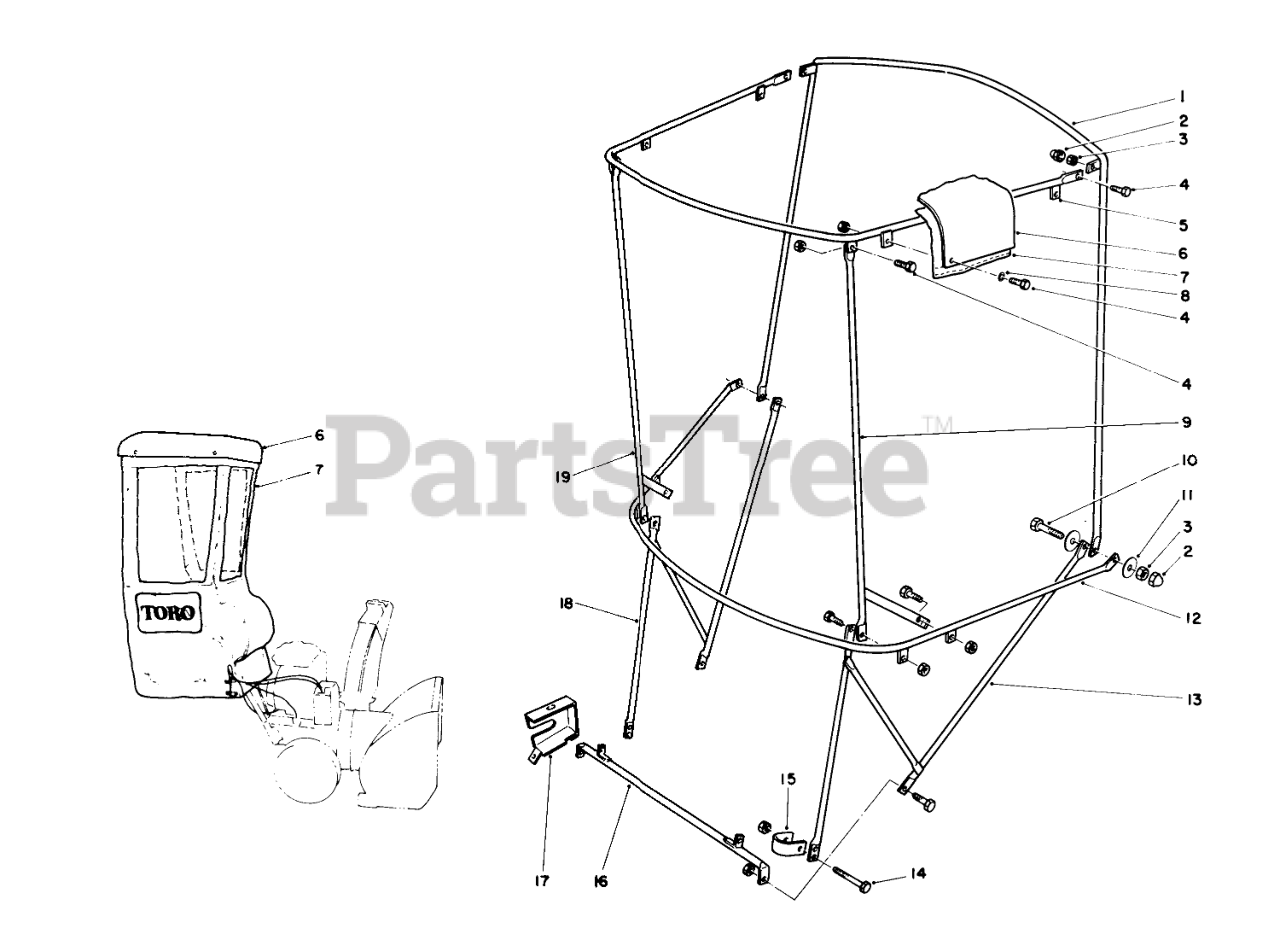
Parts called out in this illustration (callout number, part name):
1	VERTICAL BOW
2	CAPLUG
3	NUT-HEX, SIDE DEFORM
4	SCREW-HH
5	FRAME - TOP
6	Top-Plastic
7	Cover-Vinyl
8	WASHER-FLAT
9	CORNER POST - LH
10	SCREW-HH
11	WASHER-FLAT
12	HORIZONTAL BOW
13	Bracket-LH
14	SCREW-HH
15	CLAMP
16	Bracket-Base
17	COVER-LOCK, LEVER
18	BRACKET-RH
19	CORNER POST - RH
